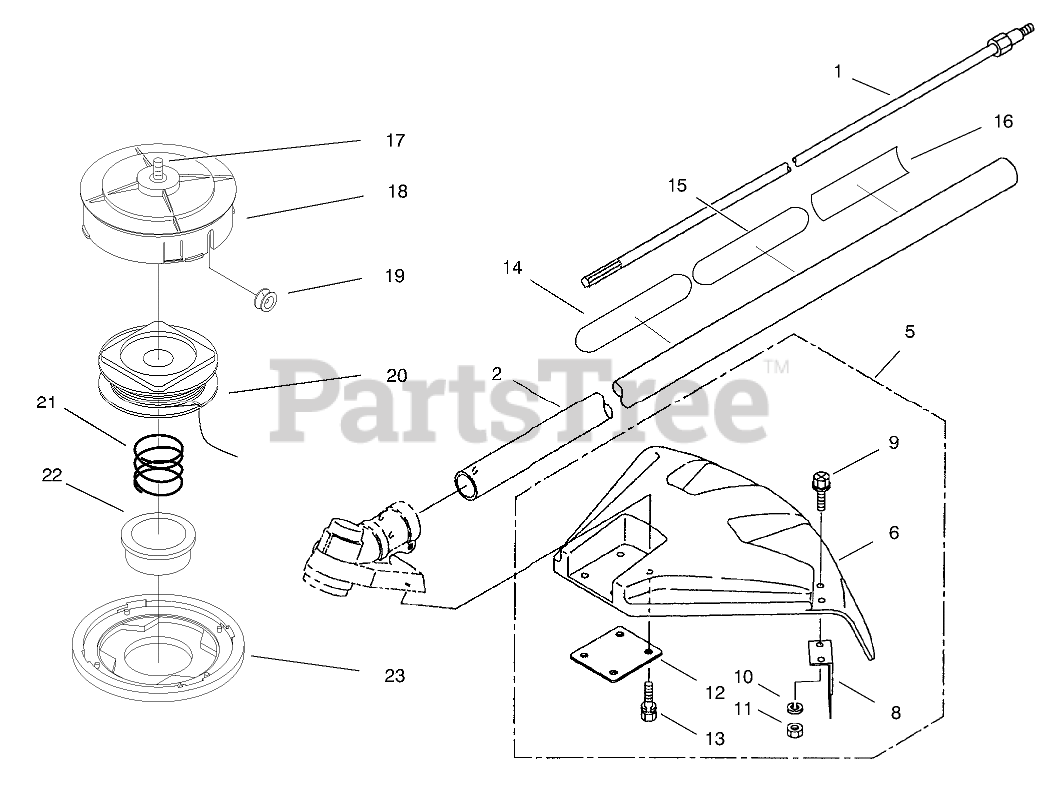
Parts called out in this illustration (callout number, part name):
1	ASM - DRIVESHAFT
2	Driveshaft Tube Assembly (Incl. Ref. #14,15)
5	Safety Cover Assembly (Incl. Ref. # 6-13)
6	COVER - SATETY
8	CUTTER - STRING
10	WASHER - SPRING
11	NUT M5
12	PLATE
14	DECAL - CAUTION
15	DECAL - CAUTION
16	DECAL - TORO
18	HOUSING
19	EYELET
20	SPOOL W/LINE (LH)
21	SPRING
22	BUTTON
23	COVER (SN-348L)
